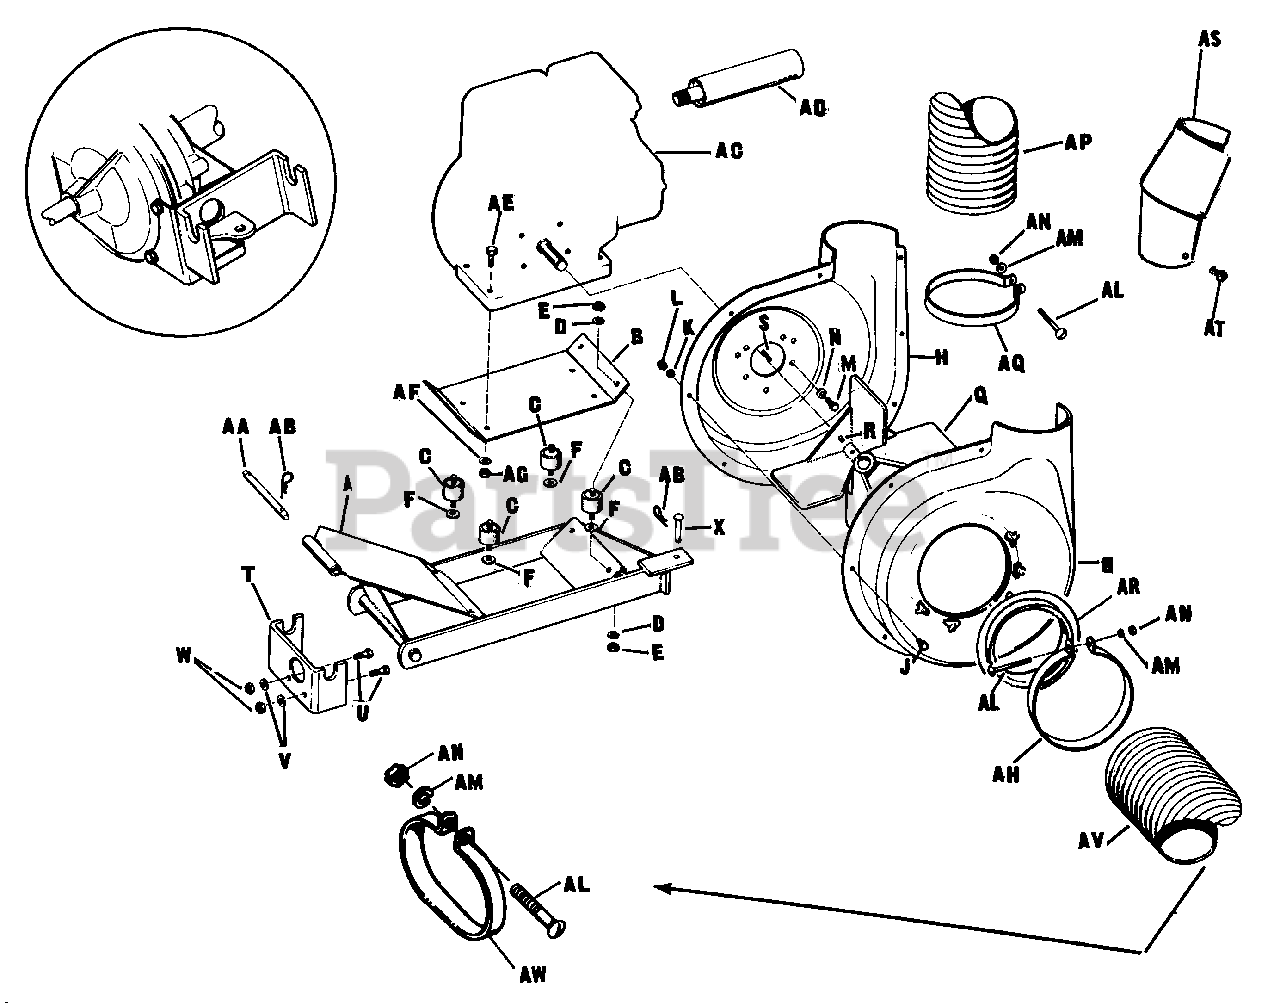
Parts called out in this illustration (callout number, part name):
A	Frame Assembly
B	Engine Plate
C	Connector, Cushion
D	Lock Washer 5/16"
E	Full Hex Nut 5/16"-18NC
F	Plain Washer 5/16"
G	Housing, Inlet Half
H	Housing Half-Blower, R.H.
J	Hex Cap Screw 1/4"-20NC x 1/2"
K	Lock Washer 1/4"
L	full Hex Nut 1/4"-20NC
M	Hex Cap Screw 5/16"-24 NF x 5/8"
N	Lock Washer 5/16"
Q	Fan Assembly
R	Set Screw 5/16"-18 x 1/2"
S	Key
U	Hex Cap Screw 3/8"-16 x 1-1/2"
V	Lock Washer 3/8"
W	Full Hex Nut 3/8"-16NC
X	Pin
AA	Counterweight Pin
AB	Clip Spring
AE	Hex Cap Screw 5/16"-18 x 1-1/2"
AF	Lock Washer 5/16"
AG	Full Hex Nut 5/16"-18NC
AH	Hose Clamp
AL	Hd. Rd. Mach. Screw 1/4"-20 x 3"
AM	Lock Washer 1/4"
AN	Full Hex Nut 1/4"-20NC
AP	Exhause Hose 6" Diameter
AQ	Hose Clamp
AR	Flange-Hose
AS	Deflector
AT	Self-Tapping Screw #lO x 3/8" lg.
AV	Intake Hose 7" Diameter
AW	Hose Clamp
